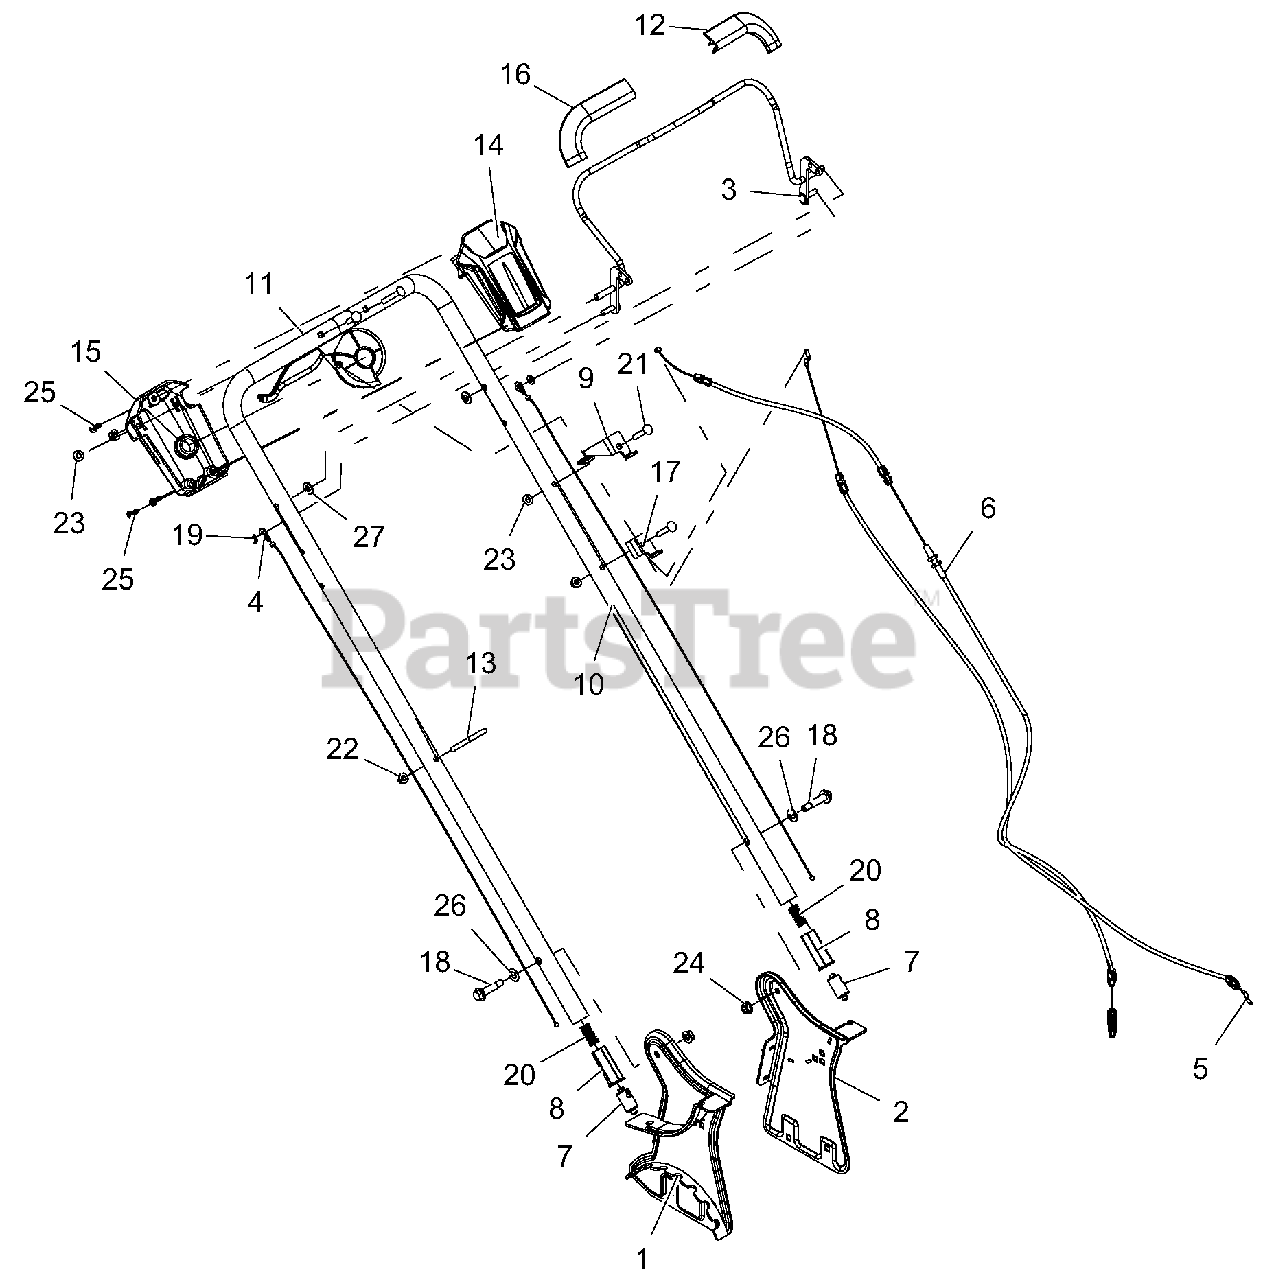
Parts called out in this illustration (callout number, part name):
1	WLDMT, RH SIDE PLATE
2	WLDMT, LH SIDE PLATE
3	BAIL, OPC
4	CABLE, LM HANDLE ADJUST
5	CABLE, OPC
6	CABLE, DRIVE CONTROL
7	PIN, LM HANDLEBAR LOCKING
8	HANDLEBAR ADJUSTMENT INSERT
9	BRKT, CABLE ANCHOR
10	HANDLEBAR,
11	HANDLE, DRIVE CONTROL
12	GUARD, FINGER - LH
13	GUIDE, RECOIL ROPE
14	HOUSING, UPPER DRIVE CONTROL
15	HOUSING, LOWER DRIVE CONTROL
16	GUARD, FINGER - RH
17	BRKT, CABLE - DRIVE
18	BLT, SHLDR .50 x 1.30 x .38-16 GR5
19	NUT, PUSH .25 x .50 O.D.
20	SPRG, COMPRESSION
21	BLT-RDHDSQNK .25-20 x 1.50 G5 Y
22	NUT-LK-NYL-FLG .25-20 YWZC
23	NUT, LK-TOP-FLG .25-20 YWZC
24	NUT, LK-TOP-FLG .312-18 YWZC
25	SCR-TAP #12-14 x .75 PLASTITE BLZC
26	WSHR-FL-STL .385 x .745 x .030 YWZC
27	WSHR-FL-STL .344 x .688 x .065 YWZC
